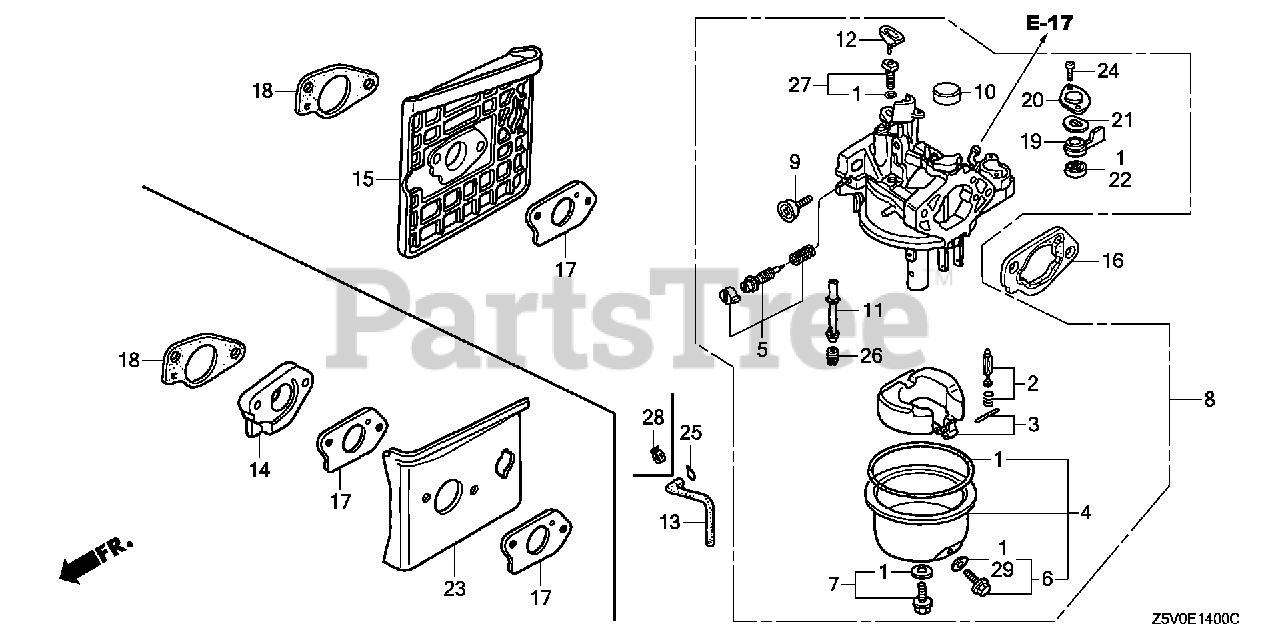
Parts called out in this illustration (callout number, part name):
1	GASKET SET (EXCEPT 16173-001-004)
2	VALVE SET, FLOAT
4	CHAMBER SET, FLOAT
5	SCREW SET (CARBURETOR NO.)
6	SCREW SET, DRAIN
7	SCREW SET
8	CARBURETOR ASSY. (BE86P C)
8	CARBURETOR ASSY. (BE86W A)
9	SCREW, THROTTLE STOP
10	CAP, CHOKE DUST
11	NOZZLE, MAIN (CARBURETOR NO.)
12	COLLAR, SETTING
13	TUBE, AIR VENT (75MM)
15	INSULATOR, CARBURETOR
16	SPACER, CARBURETOR
17	GASKET, CARBURETOR
18	GASKET, INSULATOR
19	LEVER, PETCOCK
20	PLATE, LEVER SETTING
21	SPRING, PETCOCK LEVER
22	GASKET, PETCOCK
24	SCREW, PAN (3X6)
25	CLIP, TUBE (B8)
26	JET, MAIN (#88) (CARBURETOR NO.)
26	JET, MAIN (#90)
26	JET, MAIN (#92) (CARBURETOR NO.)
26	JET, MAIN (#95) (CARBURETOR NO.)
27	JET SET, PILOT (#40)
